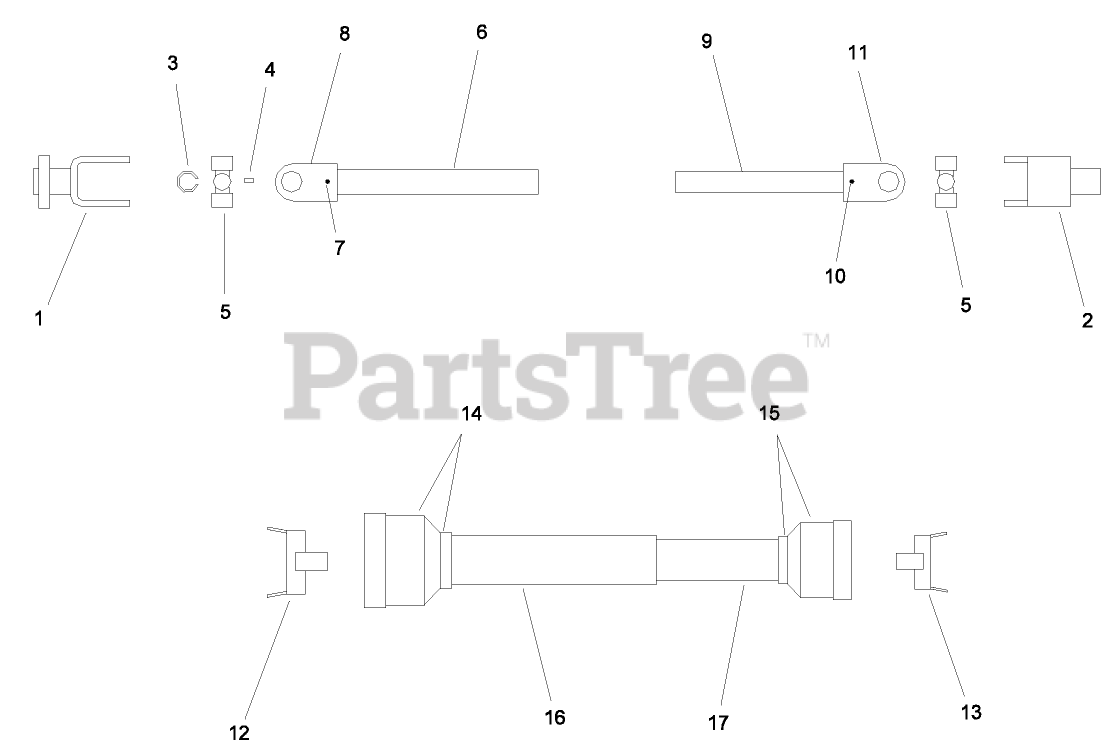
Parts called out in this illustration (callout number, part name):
2	TORQUE LIM. SA4/5
4	FITTING-GREASE
5	JOINT-CROSS, PTO
6	CM CARDAN TUBE
7	PIN-FLEXIBLE
8	YOKE-TUBE, OUTER
9	CM CARDAN TUBE MALE
10	PIN-FLEXIBLE
11	YOKE-TUBE, INNER
12	BEARING-SHIELD
13	BEARING-SHIELD
14	CONE-TUBE, OUTER
15	CONE-TUBE, INNER
16	OUTER SHIELD
17	INNER SHIELD
